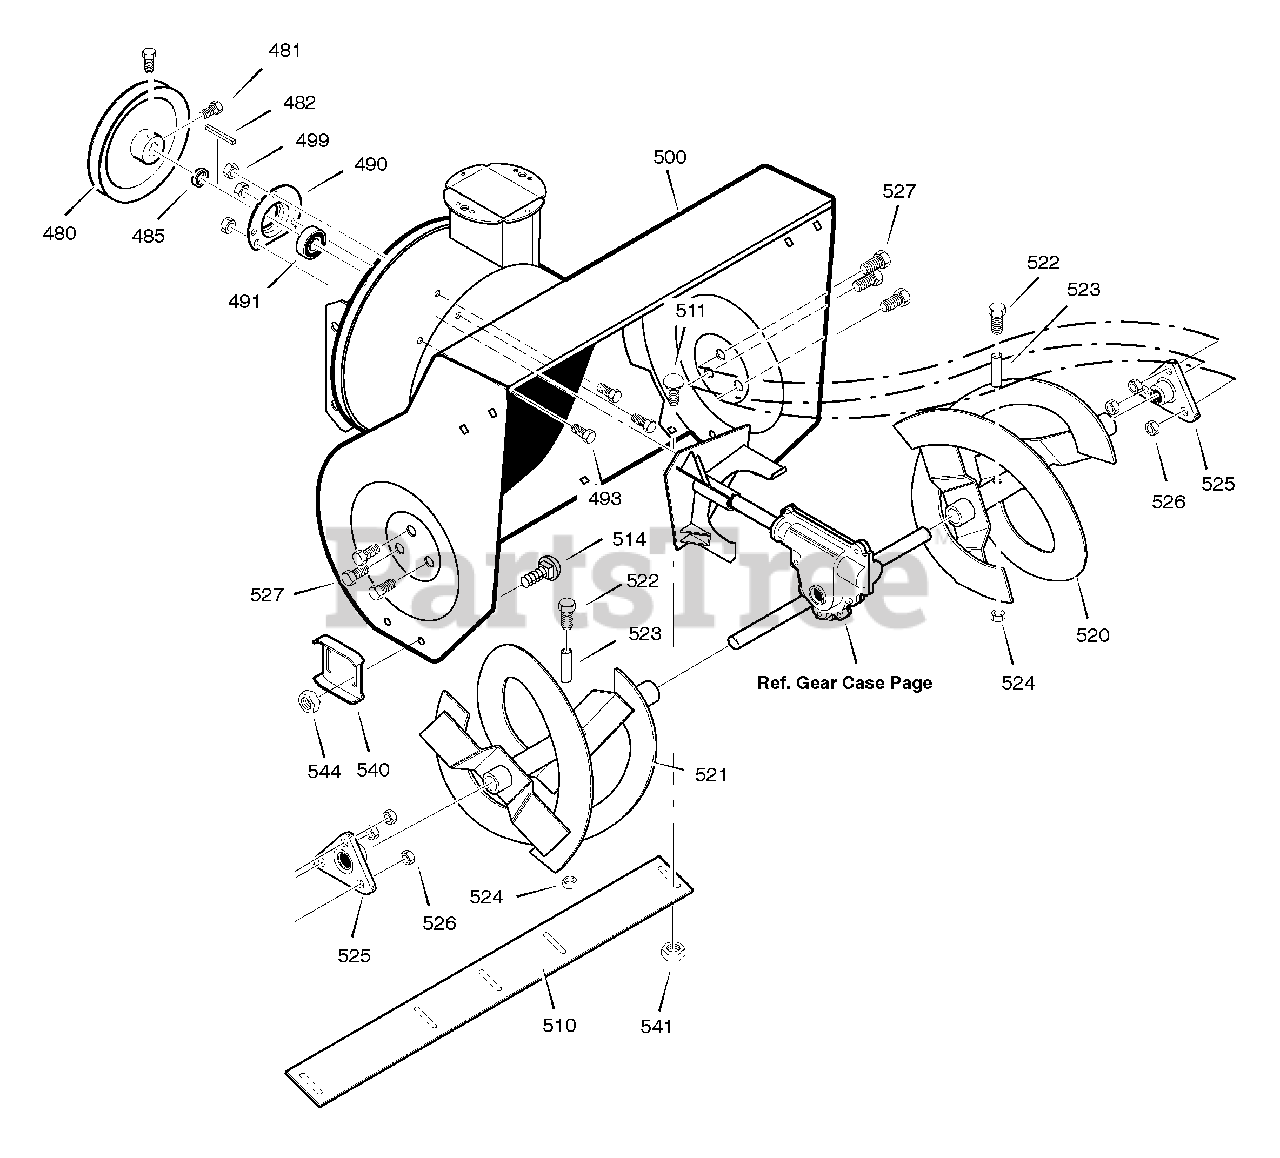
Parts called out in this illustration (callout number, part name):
480	PULLEY, 4L 6.12x0.67
481	SCREW, 5/16-18 x 0.63
482	KEY, SQUARE 3/16x3/4
485	SPACER, FRICTION PULLEY
490	RETAINER, BALL BRNG
491	BEARING, BALL
493	BOLT, HEX 5/16-18x0.50
499	NUT, 5/16-18 HEXWDFLLK
500	HOUSING, ASSY
510	BLADE, SCRAPER
511	BOLT, 5/16-18x0.62
514	NUT, 5/16-18
520	AUGER, ASSY, LH
521	AUGER, ASSY, RH
522	SCREW, 1/4-20x1.75
523	SPACER, SLEEVE
524	NUT, 1/4-20
525	BEARING, FLANGE
526	NUT, 5/16-18
527	SCREW, 5/16-18 x 0.75
540	SKID, HEIGHT ADJUST
541	BOLT, 5/16-18x0.50
544	NUT, 5/16-18
